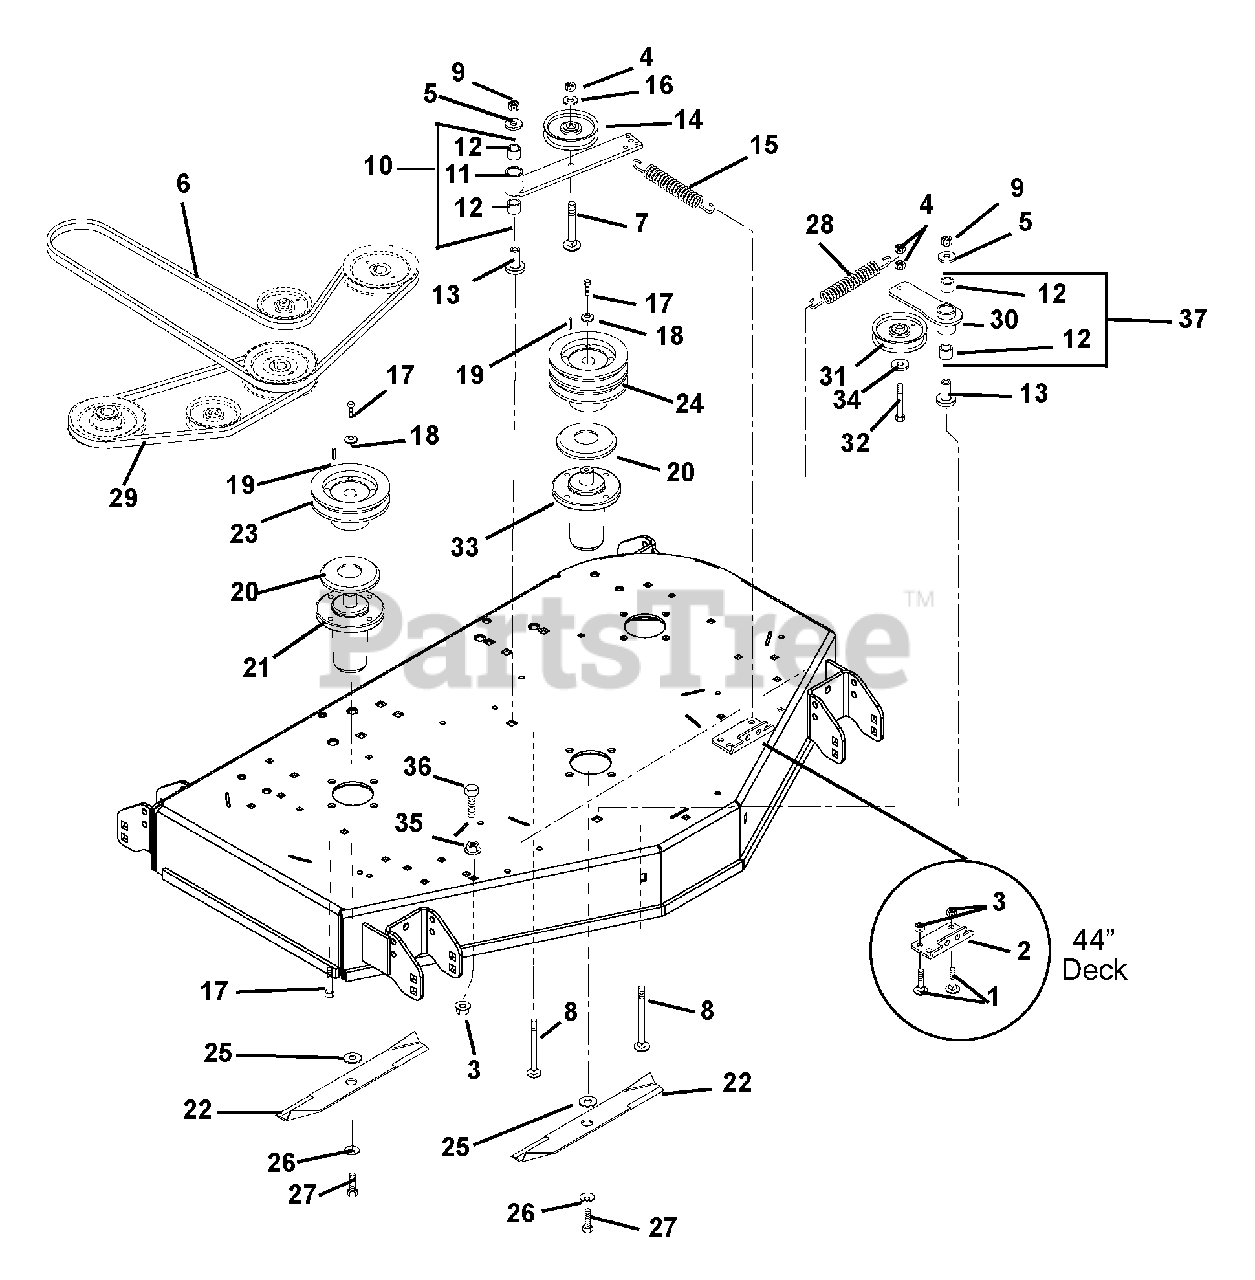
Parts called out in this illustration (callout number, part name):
1	@BLT-RDHDSQNK .38-16X.75 G5YZ
2	BRACKET, SPRING
3	@NUT-LK-TOP-FLG .38-16 YWZC
4	@NUT-LK-CTR .38-16 YWZC
5	WSHR-FL-STL .531X1.250X.10 YWZ
6	V-BELT, HB-WRAPPED
7	@BLT-RDHDSQNK .38-16X2.75 G5YZ
8	@BLT-RHDSSQNK .50-13X3.50 G5YZ
9	@NUT-LK-TOP-FLG .50-13 YWZC
10	ASSEMBLY - IDLER PIVOT ARM
11	WMT - IDLER PIVOT ARM
12	BRG, 1.00 X 1.12 X .75
13	BEARING, PEDESTAL
14	IDLER-FLAT 4.00X.38 (2.00 W)
15	SPRING, EXT0NSION DIA1.0X6.0LG
16	WSHR-FL-STL .375X1.125X.065YWZ
17	BLT-HEX .38-16X1.0 GR8 YZ EP30
18	WSHR,FLT STL.406X1.50X.245YWZC
19	KEY, SQ .25X.25X1.00 RC 40-50
20	SLINGER, DUST
21	ASM,MAINT FREE SPINDLE
22	BLADE, 32" (16.25)
22	BLADE, MULCH 16.25
23	WELDMENT, SPINDLE SHEAVE 5.00
24	SHEAVE, DOUBLE (5.25")
25	WSHR-FLT .640X1.75X.250 YWZC
26	WSHR-BLVL .669X1.535X.138
27	BLT-HEX .62-18X1.75 GR8 YWZC
28	SPRING, EXT
29	V-BELT, 5L-RAW EDGE
30	WMT, IDLER PIVOT ARM
31	V-IDLER, 4.00X.38
32	@BLT-HEX .38-16X2.25 GR5 YWZC
33	ASM,MAINT FREE SPINDLE
34	@WSHR-FL-STL.406X.812X.065 YWZ
35	@NUT-SPNLK-FLG .375-16 YWZC
36	@BLT-HEX .38-16X3.50 GR5 YWZC
37	ASM, IDLER PIVOT ARM
